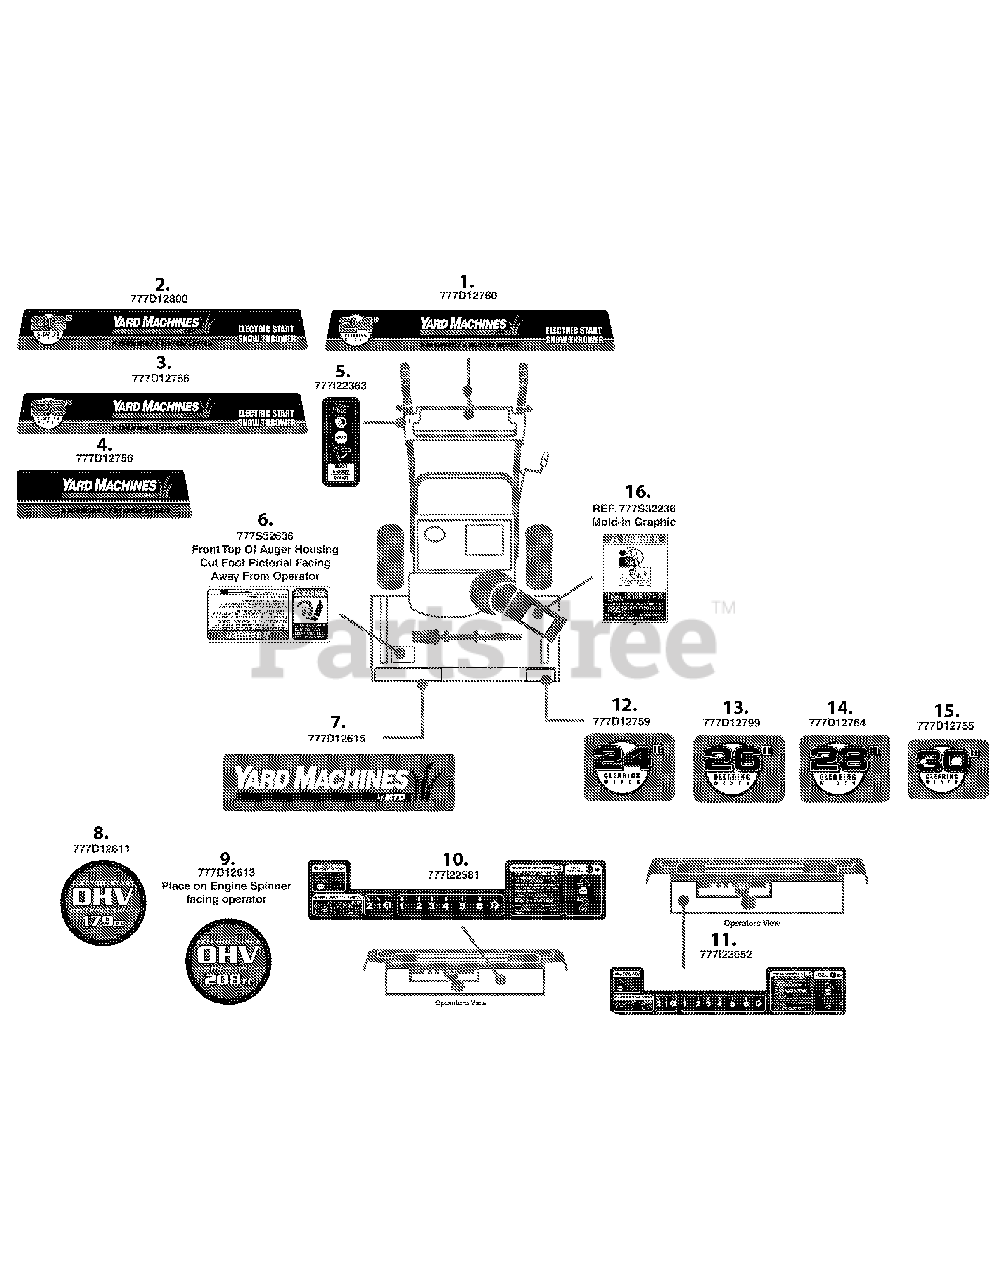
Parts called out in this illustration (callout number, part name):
1	LABEL:SNOW:HNDLPANL:YMACH:24/6/2
2	LABEL:SNOW:HNDLPANL:YMACH:26/6/2
3	LABEL:SNOW:HNDLPANL:YMACH:28/6/2
4	LABEL:SNOW:FRT/HNDL/PAN:YM:6/2
5	LABEL:DRV/AUGR LOCK
6	LABEL:SNOW HOUSING
7	LABEL:SNOW:FRNT/LFTAUG:YMACH
8	LABEL:ENG/SPN:OHV/ES/179
9	LABEL:ENG/SPN:OHV/ES/208
10	LABEL:OPERATOR PAN
11	LABEL:SNOW:E/F PNL:ST INSTR:B&S
12	LABEL:SNOW:FRNT/RTAUG:YMACH:24
13	LABEL:SNOW:FRNT/RTAUG:YMACH:26
14	LABEL:SNOW:FRNT/RTAUG:YMACH:28
15	LABEL:SNOW:FRNT/RTAUG:YMACH:30
16	LABEL:SNOW CHUTE
